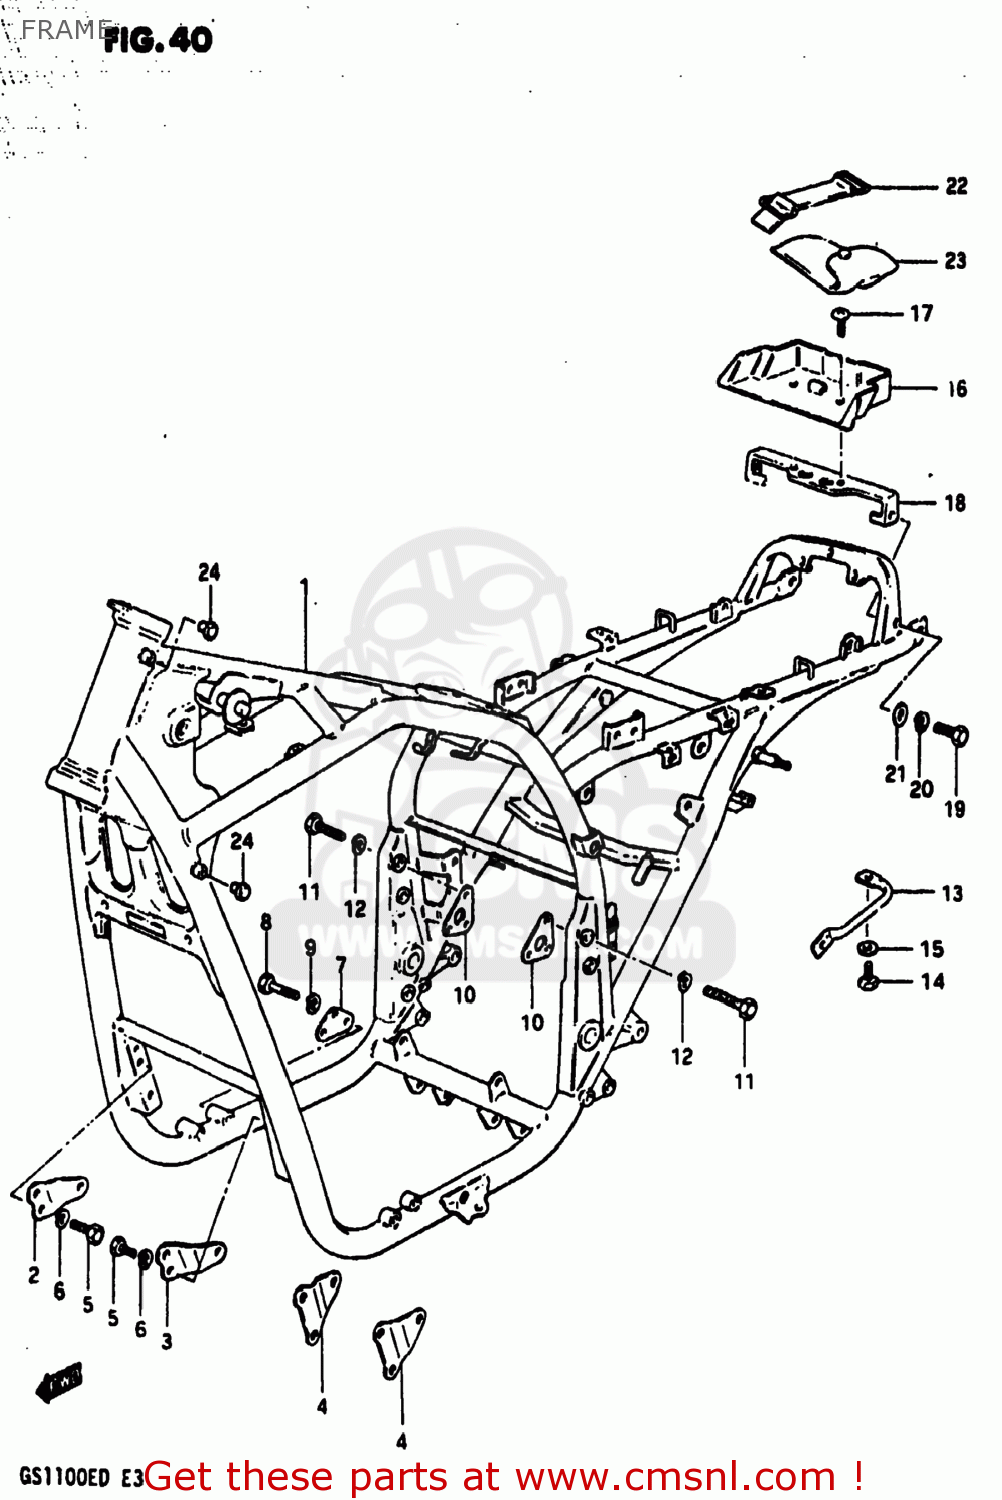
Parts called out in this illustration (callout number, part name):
1	FRAME
2	PLATE,ENGINE MOUNTING NO
3	PLATE,ENGINE MOUNTING NO
4	PLATE,ENGINE MOUNTING
5	BOLT
6	LOCK WASHER
7	PLATE,ENGINE MOUNTING
8	BOLT
9	LOCK WASHER
10	PLATE,ENGINE MOUNTING
11	BOLT
12	LOCK WASHER
13	GRIP,FRAME HANDLE
14	BOLT
15	WASHER
16	HOLDER,TOOL
17	SCREW
18	PLATE,TOOL HOLDER
19	BOLT
20	LOCK WASHER
21	WASHER
22	BAND
23	TOOL ASSY
24	PLUG(OD:12)
